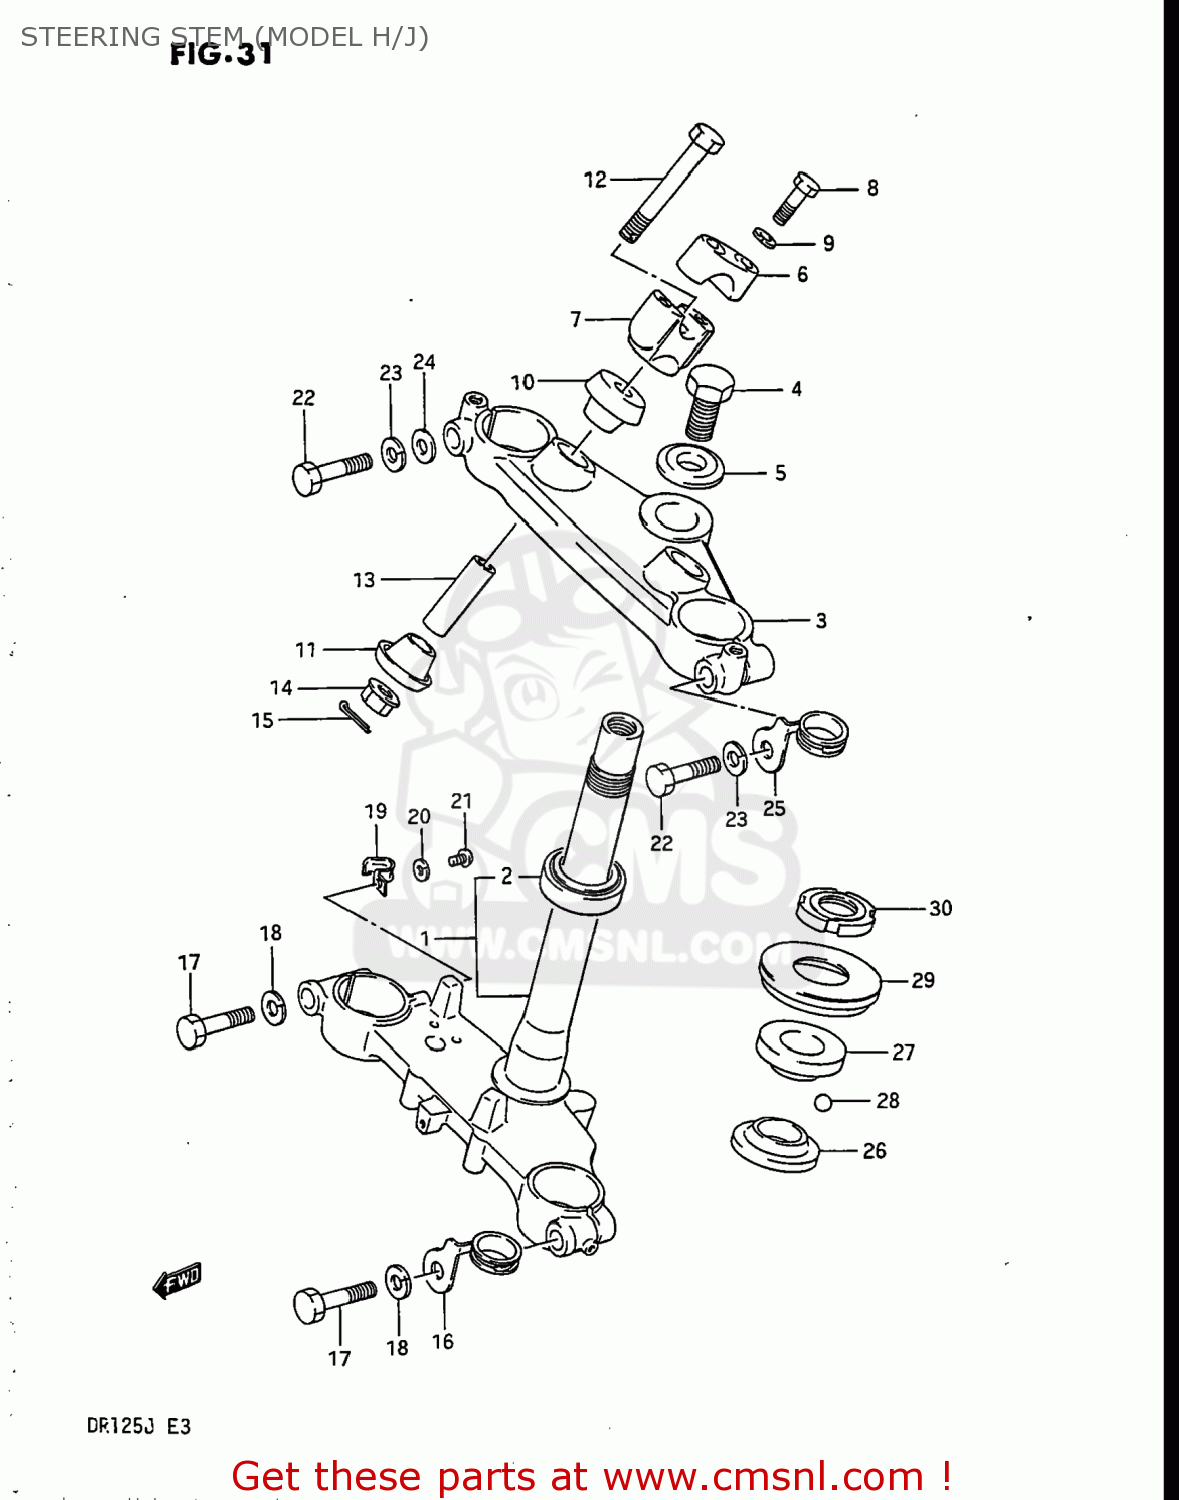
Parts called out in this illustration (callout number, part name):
1	STEM,STEERING
2	BEARING
3	HEAD,STEERING STEM
4	BOLT,STEERING STEM HEAD
5	WASHER
6	HOLDER,HANDLE UPR
7	HOLDER,HANDLEBAR LWR
8	BOLT
9	WASHER,LOCK,8.
10	RUBBER,HANDLE HOLDER
11	RUBBER,LWR
12	BOLT
13	SPACER
14	NUT
15	COTTER PIN
16	CLIP,UPPER
17	BOLT,INNER TUBE FITTING
18	WASHER,LOCK
19	CLIP
20	WASHER,LOCK
21	SCREW
22	BOLT,INNER TUBE FITTING
23	WASHER,LOCK
24	WASHER 10MM
25	CLIP,UPPER
26	RACE,STEERING INNER (SUJ)
27	RACE,STEERING,OUTER,UPPER
28	BALL
29	SEAL,STEERING UPR DUST
30	NUT,STEERING STEM
